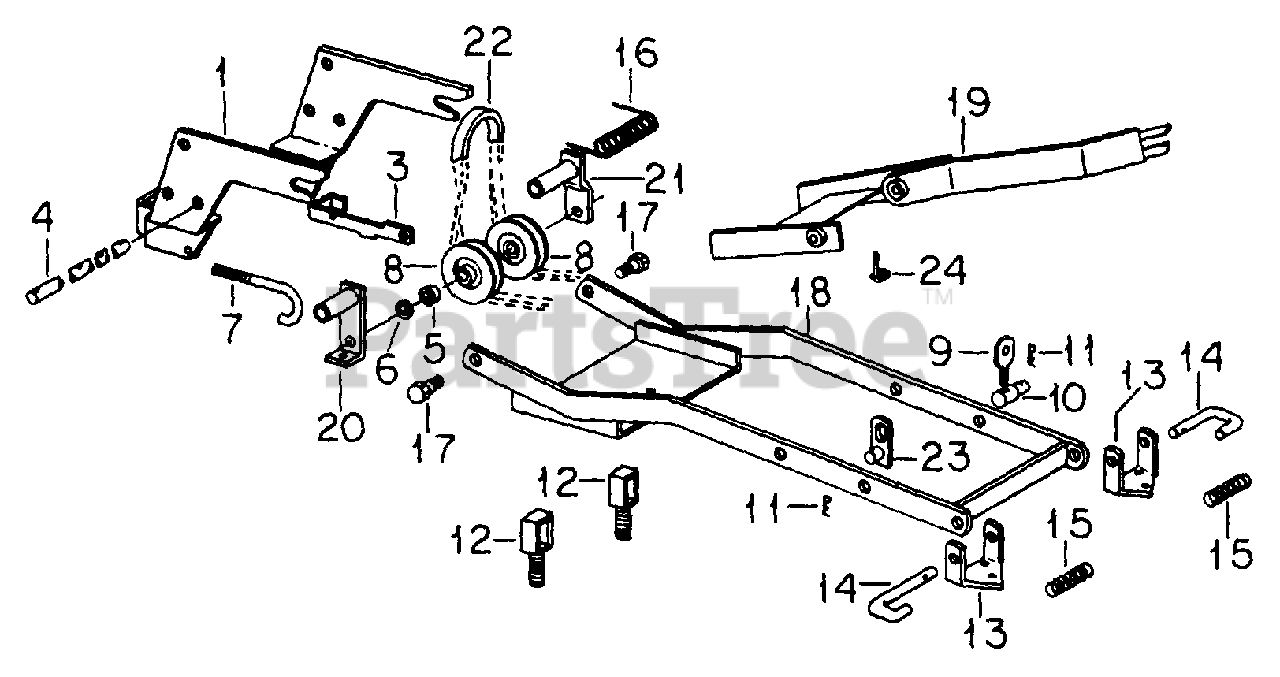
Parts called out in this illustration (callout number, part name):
1	HANGER ASSY, FRONT
3	SUPPORT, IDLER RATCHET
4	SHAFT, IDLER PIVOT
5	SPACER, .390 x .625 .500
6	WASHER, WAVE
7	BOLT, IDLER ADJUSTER
8	PULLEY, DRIVE BELT IDLER
9	LINK, ADJUSTABLE
10	BLOCK, ADJUSTABLE
11	PIN, QUICK ATTACHABLE COTTER
12	HANGER, MOWER SUPPORT FRONT
13	BRACKET, MOWER SUPPORT
14	PIN, MOWER SUPPORT
15	SPRING, MOWER SUPPORT PIN
16	SPRING, MULE DRIVE IDLER
17	BOLT, SHOULDER
18	FRAME ASSY, OUTER LIFT
19	FRAME ASSY, CENTER
20	ARM ASSY, LH IDLER
21	ARM ASSY, RH IDLER
22	BELT, MULE DRIVE
18481-R1	PIN, 3/16 x 1 COT
251040-R1	NUT, 1/2 PLN PJTN WELD PILOT
1254812-C1	BRACE, WEIGHT BRACKET
